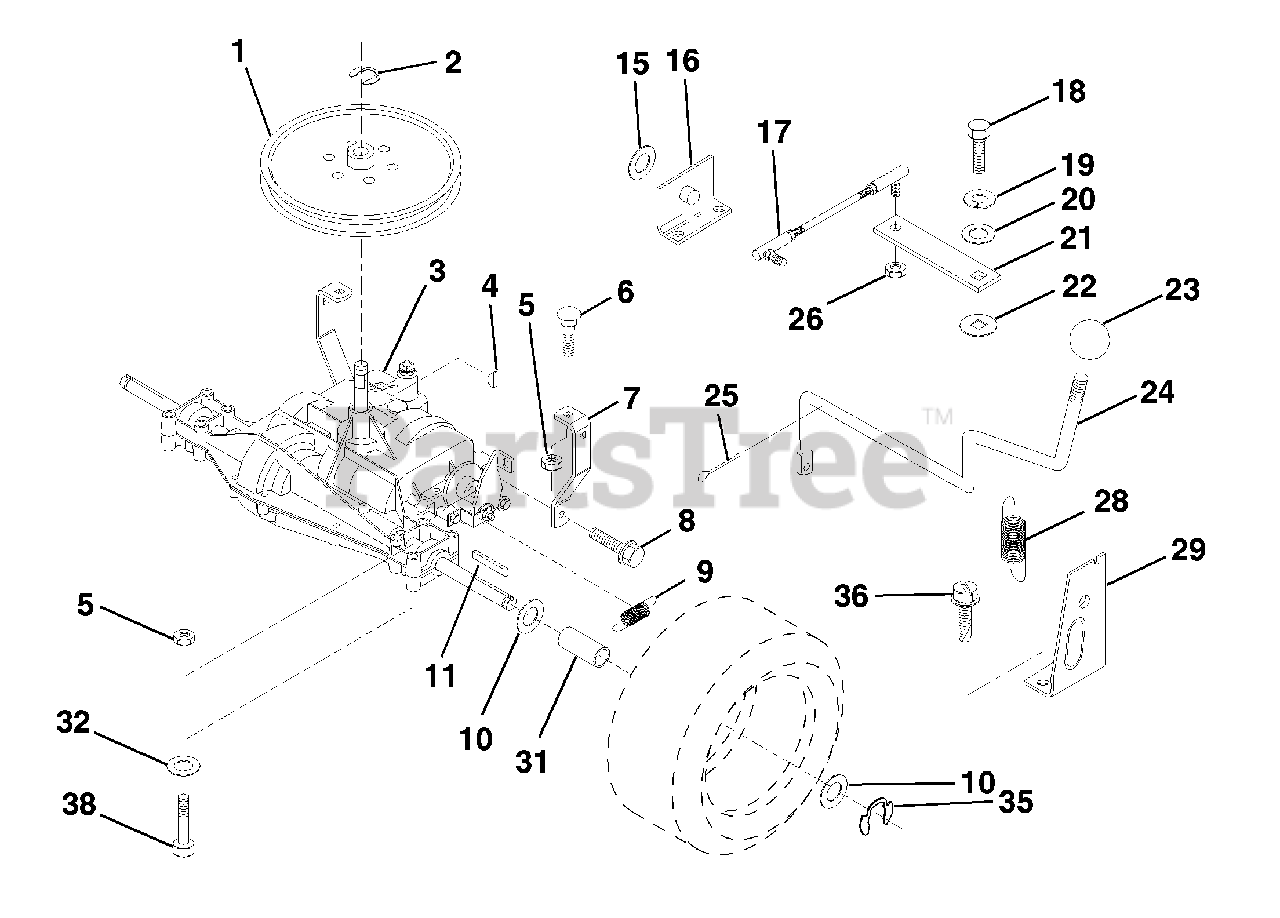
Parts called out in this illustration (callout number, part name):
2	Ring, Retainer
3	Transaxle
4	Key, Woodruff #9
5	Nut, Crownlock 5/16-18
6	Bolt, Carriage 5/16-18 UNC x 3/4
7	Strap, Torque
8	Screw 5/16-18 x 3/4
9	Spring, Brake
10	Washer 25/32 x 1-1/4 x 16 Ga.
11	Key, Square
15	Washer 17/32 x 1 x 16 Ga.
16	Support Handle Shift LH
17	Link, Shift
18	Bolt, Fin Hex 1/4-28 UNF x 3/4 Gr. 8
19	Washer, Lock 1/4
20	Washer 9/32 x 3/4 x 10 Ga.
21	Arm, Shift
22	Washer, Shift Plate
23	Knob, Rd 1/2-13
25	Pin, Cotter 1/8 x 1
26	Locknut 5/16-24 UNF
28	Extension, Spring
29	Support Handle Shift RH
31	Spacer Axle
32	Washer 11/32 x 11/16 x 16
36	Screw, Thd Cut 1/4-20 x 1/2
38	Bolt, Hex Hd 5/16-18 x 2-3/4
